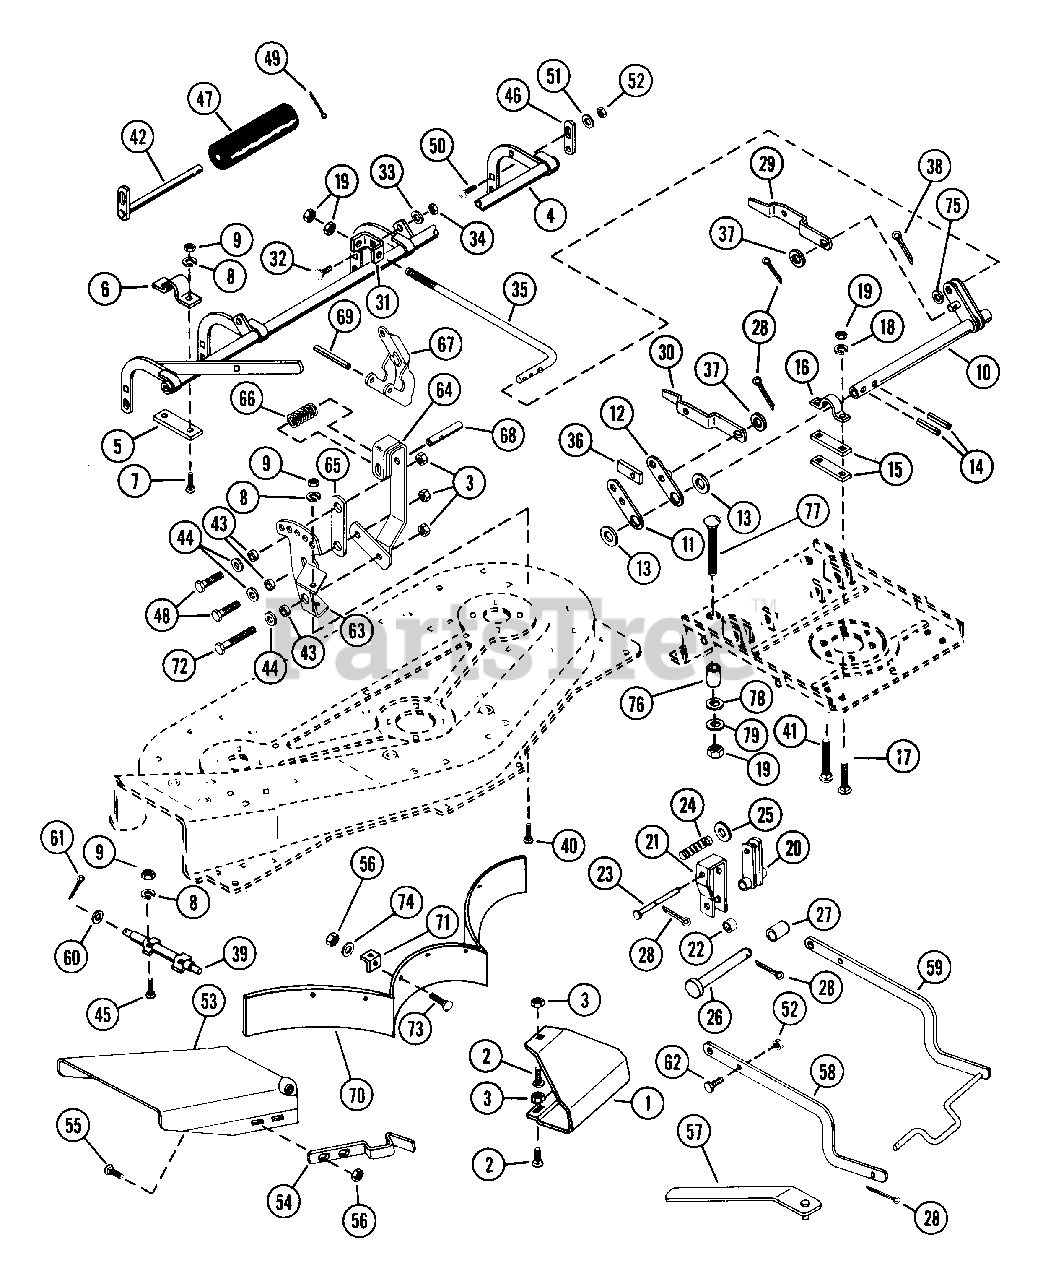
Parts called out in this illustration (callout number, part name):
1	SKID 42 INCH MOWER
2	BLT-RDHDSQSHNK .31-18X.50 YZ
3	NUT-LK .312-18 GR A PL
4	ROLLER FRAME 42 INCH
5	ADJUSTMENT PLATE
7	BLT-RDHDSQNK .31-18X1.0 SHT PL
8	WSHR-LK .312X.097 PL HVY
9	NUT-HEX .312-18
10	FRONT HANGER
11	OUTSIDE LINK
12	INSIDE LINK
13	WSHR-FL-STL .781X1.250X.059 PL
14	PIN-ROLL .250X1.25
17	BLT-RDHDSQNK .50-13X1.50 PL
18	WSHR-LK .500X.151 HVY PL
19	NUT .50-13 PL
21	SUPPORT CHANNEL
22	SPACER .516X.749X.938
23	PIN-CLEV .498X4.31 YWZC
24	SG-COMP .62X.68X1.75
25	WSHR-FL-STL .531X1.062X.095 PL
26	PIN-CLEV .498X4.50 YWZC
27	SPACER .390X1.000X.562
28	PIN-COTR .12X1.0 PL
29	LEVELING LEVER L.H.
30	LEVELING LEVER R.H.
32	BLT-RDHDSQNK .50-13X1.25 PL
33	WSHR-FL-STL .505X.880X.072 PL
34	NUT-LK-CTR .50-13
35	ADJUSTMENT ROD
36	WEAR PLATE
37	WSHR-FL-STL .511X1.441X.125 PL
38	PIN-COTR .12X.75 PL
39	HINGE PIN
40	BLT-SERRDHD SL .31-18X.75 YZ
41	BLT-RDHDSQNK .50-13X1.75 PL
42	ROLLER SHAFT
43	SPACER BUSHING .5 X .32 X .21
44	WSHR-FL-STL .328X.875X.062 PL
45	BLT-HEX .31-18X.75 PL GR5
48	BLT-HEX .31-18X.75 PL GR2
49	PIN-COTR .18X1.0 PL
50	BLT-RDHDSQSHNK .38-16X1.00 PL
51	WSHR-FL-STL .438X1.0X.083 PL
52	NUT-LK-CTR .375-16 GR A PL
53	CHUTE EXTENSION
54	SPRING, FLAT
55	BLT-RDHDSQNK .25-20X.50 SHT PL
56	NUT-LK-CTR .250-20 PL
58	HANGER ARM
59	MOWER HANGER
60	WSHR-FL-STL.406X.812X.065PL
61	PIN-COTR .09X.75 PL
62	BLT-HEX .38-16X1.00 PL GR5
63	QUADRANT
64	HANDLE HEIGHT ADJ.
66	SG-COMP .045X.50X1.187
69	PIN-ROLL .188X1.75
72	BLT-HEX .31-18X1.25 PL GR5
73	BLT-RDHDSQNK .25-20X.50 SHT PL
74	WSHR-FL-STL.281X.62X.065 PL
75	WSHR-FL-STL .469X.937X.065 PL
76	SPACER .512X.747X1.567
77	BLT-RDHDSQNK .50-13X2.75 SHTPL
78	WSHR-FL-STL .505X.880X.072 PL
79	WSHR-FL-STL .511X1.441X.125 PL
